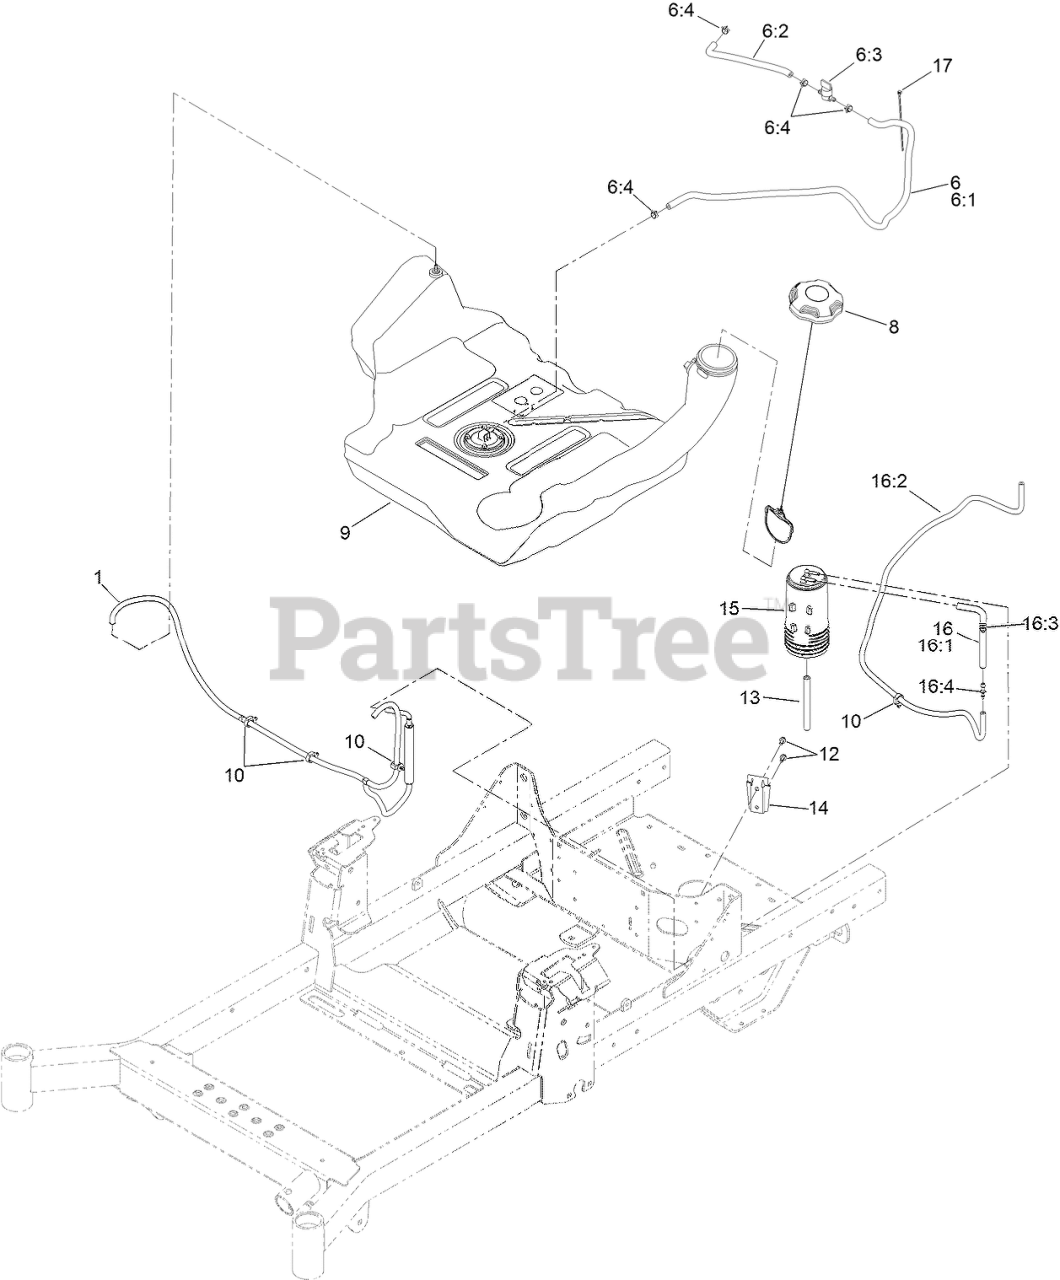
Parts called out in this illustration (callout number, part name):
1	VENT HOSE ASM
6	FUEL HOSE ASM
6:1	HOSE-FUEL
6:2	HOSE-FUEL
6:3	VALVE-FUEL
6:4	CLAMP-HOSE
8	CAP-FUEL, RATCHETING
9	TANK-FUEL
12	SCREW-HWH
13	HOSE-FUEL
14	BRACKET-CANISTER, CARBON
15	CANISTER-CARBON, 800CC
16	VENT HOSE ASM
16:1	HOSE-FUEL
16:2	HOSE-FUEL
16:3	CARTRIDGE-VALVE, CHECK
16:4	FITTING-STRAIGHT
17	TIE-CABLE
